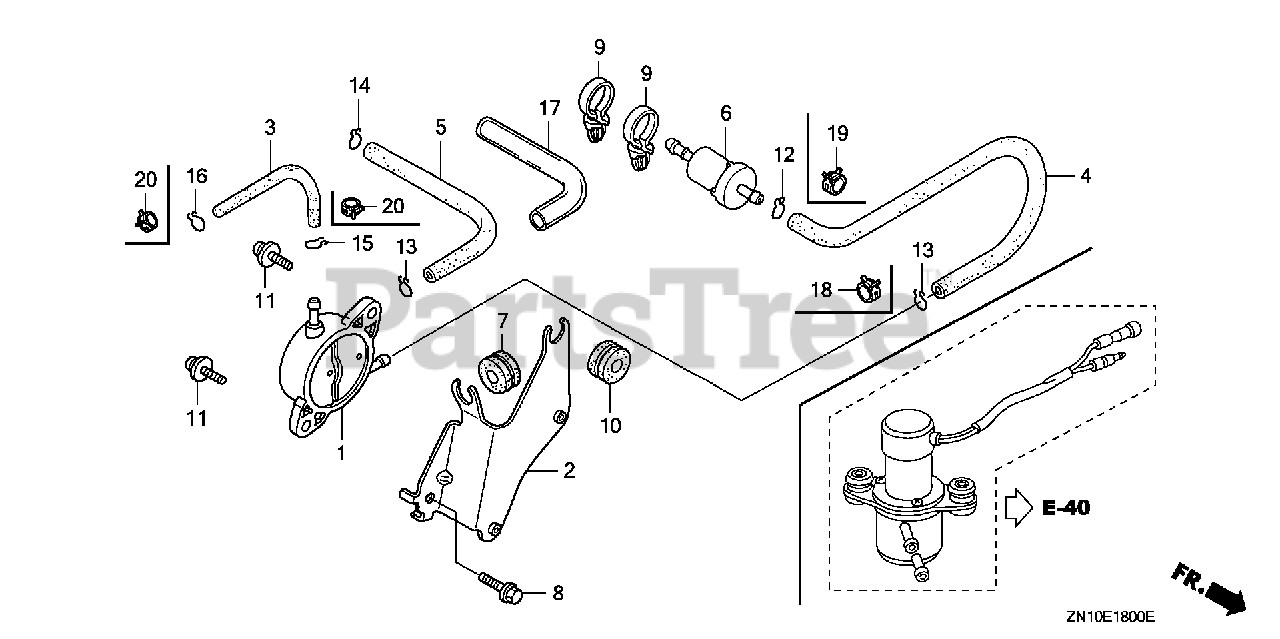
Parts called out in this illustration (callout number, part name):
1	PUMP ASSY., FUEL
2	STAY, FUEL PUMP
3	TUBE, FUEL
4	TUBE B, FUEL
5	TUBE, DIAPHRAGM
6	STRAINER, FUEL
7	GROMMET, RESERVE TANK
8	BOLT, FLANGE (6X14) (CT200)
9	CLIP, WIRE HARNESS
10	GROMMET, PUMP STAY
11	SCREW-WASHER (6X16)
12	CLIP, TUBE (B8)
13	CLIP, TUBE (B10)
14	CLIP, TUBE (C9)
15	CLIP, TUBE (C11)
16	CLIP, TUBE (B10)
